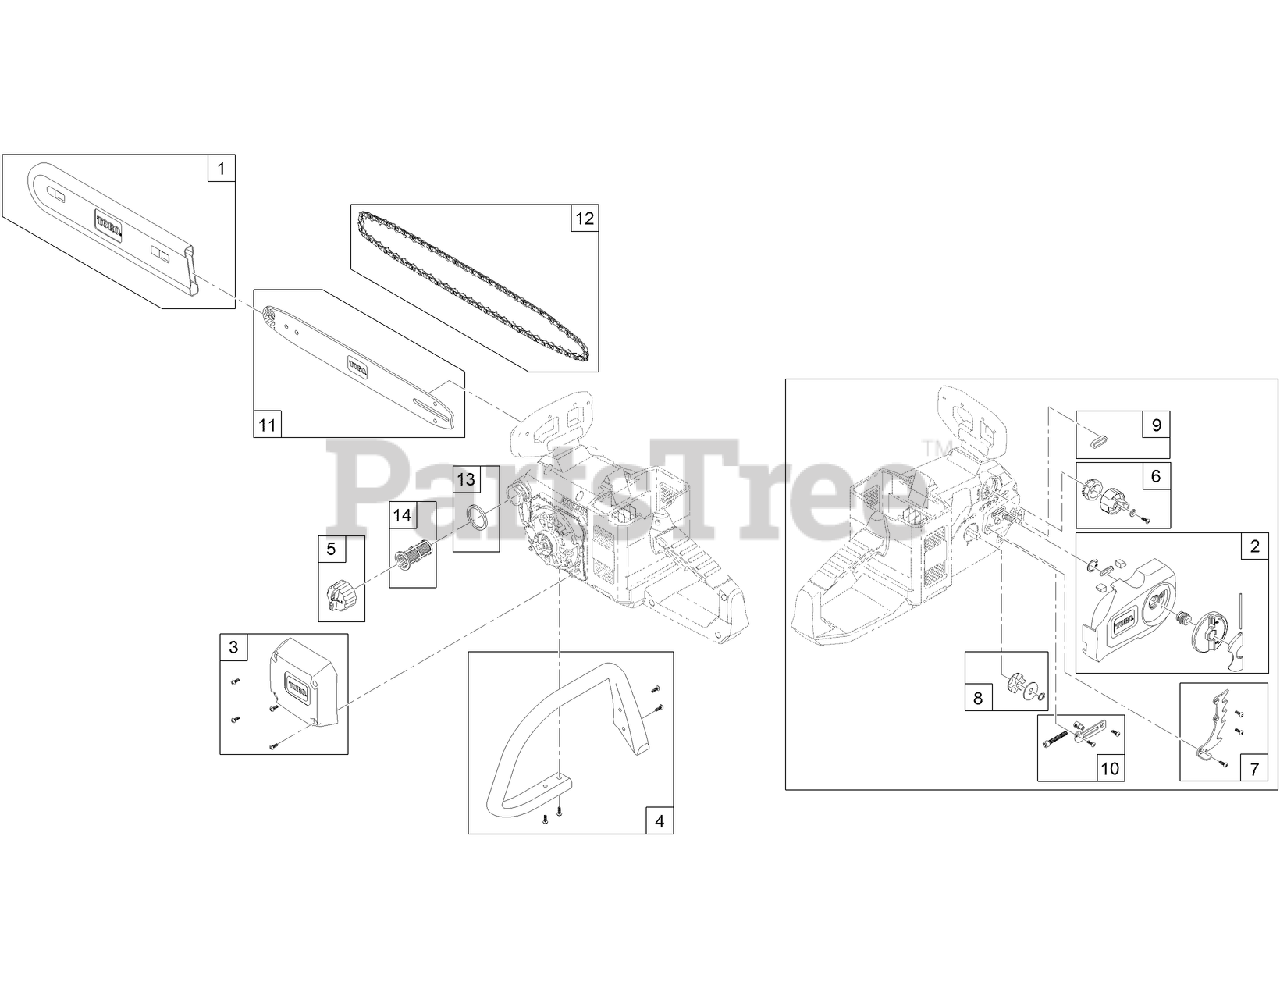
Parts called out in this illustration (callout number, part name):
1	SLEEVE-BAR/CHAIN
2	CHAIN Bar PANEL ASM
3	COVER-MOTOR
5	CAP-OIL, BAR
6	KNOB-ADJUSTER, Bar AND CHAIN
7	BUCKING TEETH BRACKET ASM
8	SPROCKET-DRIVE, CHAIN
9	GASKET-OIL, BAR/HOUSING
10	ADJUSTER-Bar PIN AND SCREW
11	Bar-REPLACEMENT
12	CHAIN-REPLACEMENT
13	GASKET-OIL CAP, BAR
14	Strainer-Oil, Bar
